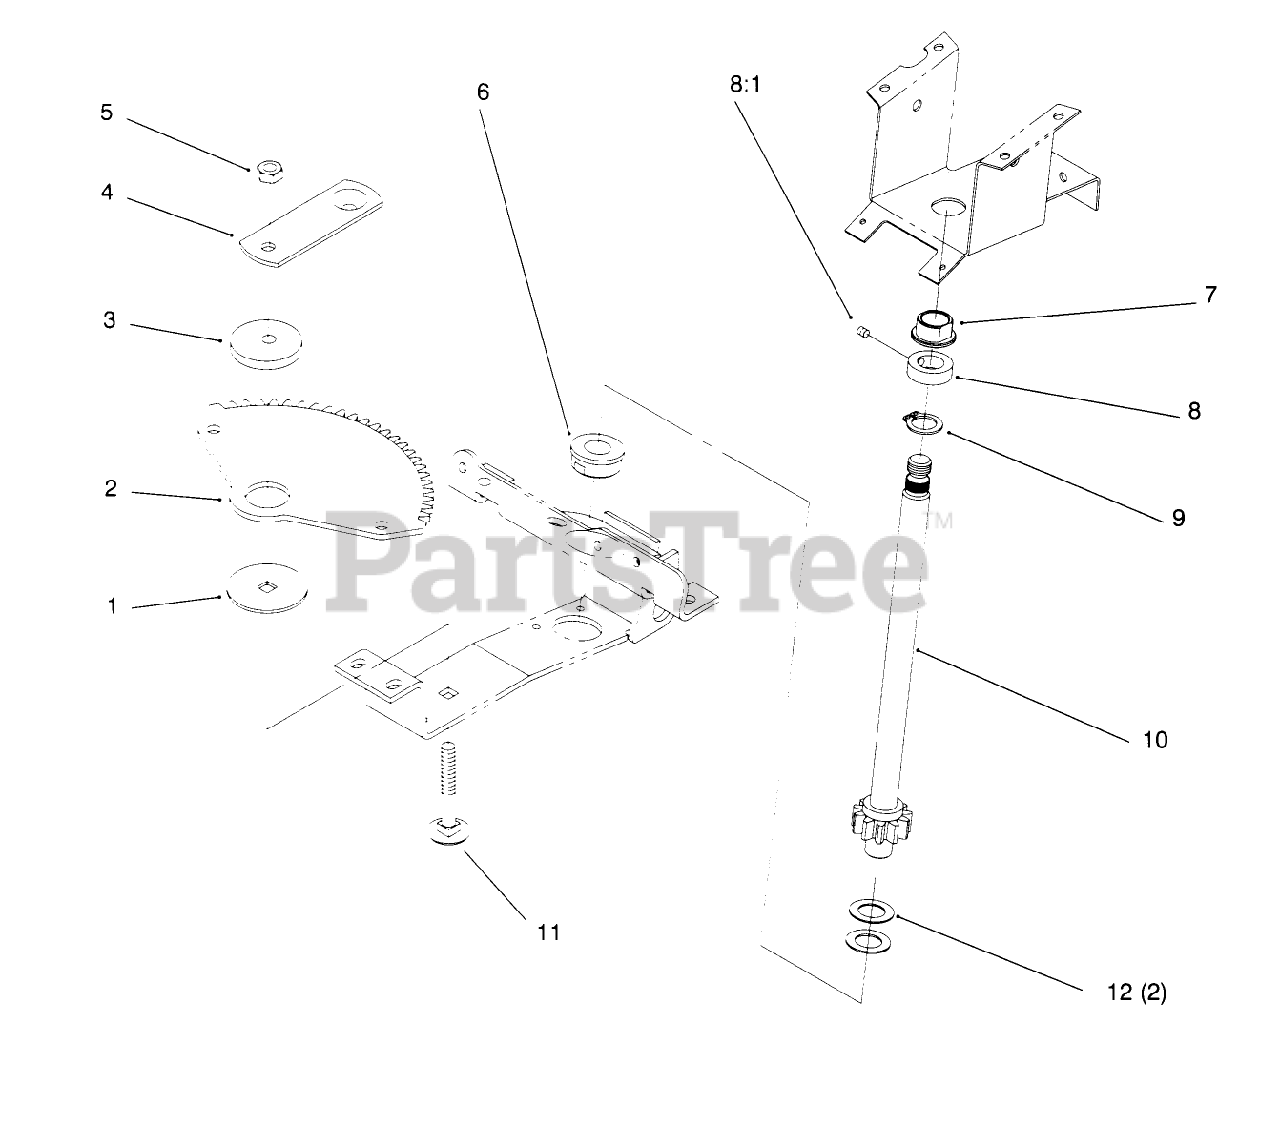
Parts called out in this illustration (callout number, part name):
1	WASHER-BEARING
3	BUSHING
5	NUT-HEX
6	BEARING-WHEEL
7	BEARING-FLANGED
8	COLLAR
8:1	SCREW-HSH
9	RING-RETAINING
10	SHAFT-STEERING, LOWER
11	SCREW-CARR
12	WASHER
